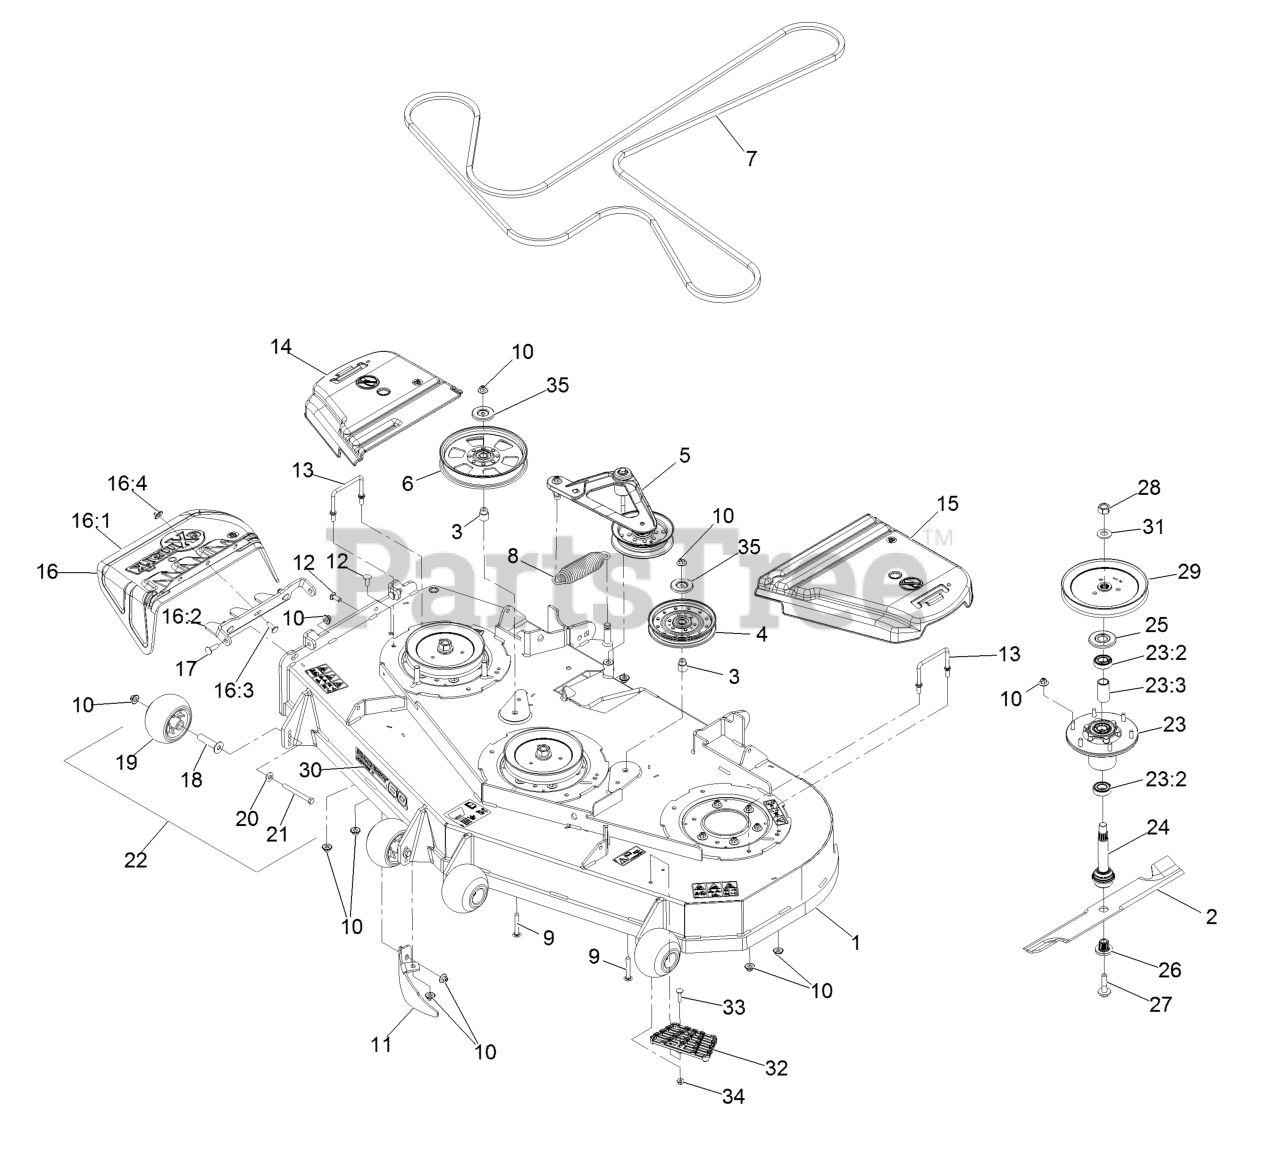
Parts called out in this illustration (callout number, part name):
1	Deck ASM,W/Decals 60
2	Blade, Solid
2	Blade, Low Lift
2	Blade, Mulching
2	Blade, Notched
2	Blade-Extreme 2, 20.50"
3	Bushing, Idler
4	Idler-Pulley
5	Deck Idler ASM
6	Pulley-Idler, Flat
7	Belt,V-5V-198.75
8	Spring-Extension
9	Bolt-Carriage 3/8-16 X 2 1/2
10	Nut-Nyloc 3/8-16 Flg
11	Dogleg - Lz60
12	Bolt-Carriage 3/8-16 X 1
13	Wireform-Cover
14	Cover-Belt, RH
15	Cover-Belt, LH
16	ASM,Discharge Chute
16:1	Chute, Discharge
16:2	Bracket,Discharge Chute
16:3	Bolt-Carriage 3/8-16 X 1
16:4	Nut-Nyloc 3/8-16 Flg
17	Bolt-Carriage 3/8-16 X 1 1/4
18	Axle, Roller
19	Roller-Anti-Scalp
20	Washer-Spring Disc 3/8
21	Screw-HH 3/8-16 X 3 3/4 GR 8
22	Kit, Anti-Scalp Roller
23	ASM-Cutter Hsg With Bearings
23:2	Bearing-Ball
23:3	Spacer-Bearing
24	ASM-Spindle And Seal
25	Guard,Bearing Top .989
26	Bushing, Splined
27	Screw-Sems 1/2-20 X 2.19
28	Nut-Hex
29	Sheave,Blade Drive 7.25
30	Decal, 604
31	Washer-Spring Disc 3/4
32	Step-Deck
33	Bolt-Carriage 5/16-18 X 1 1/4
34	Nut-Nyloc 5/16-18 Flg
35	Shield-Dust
